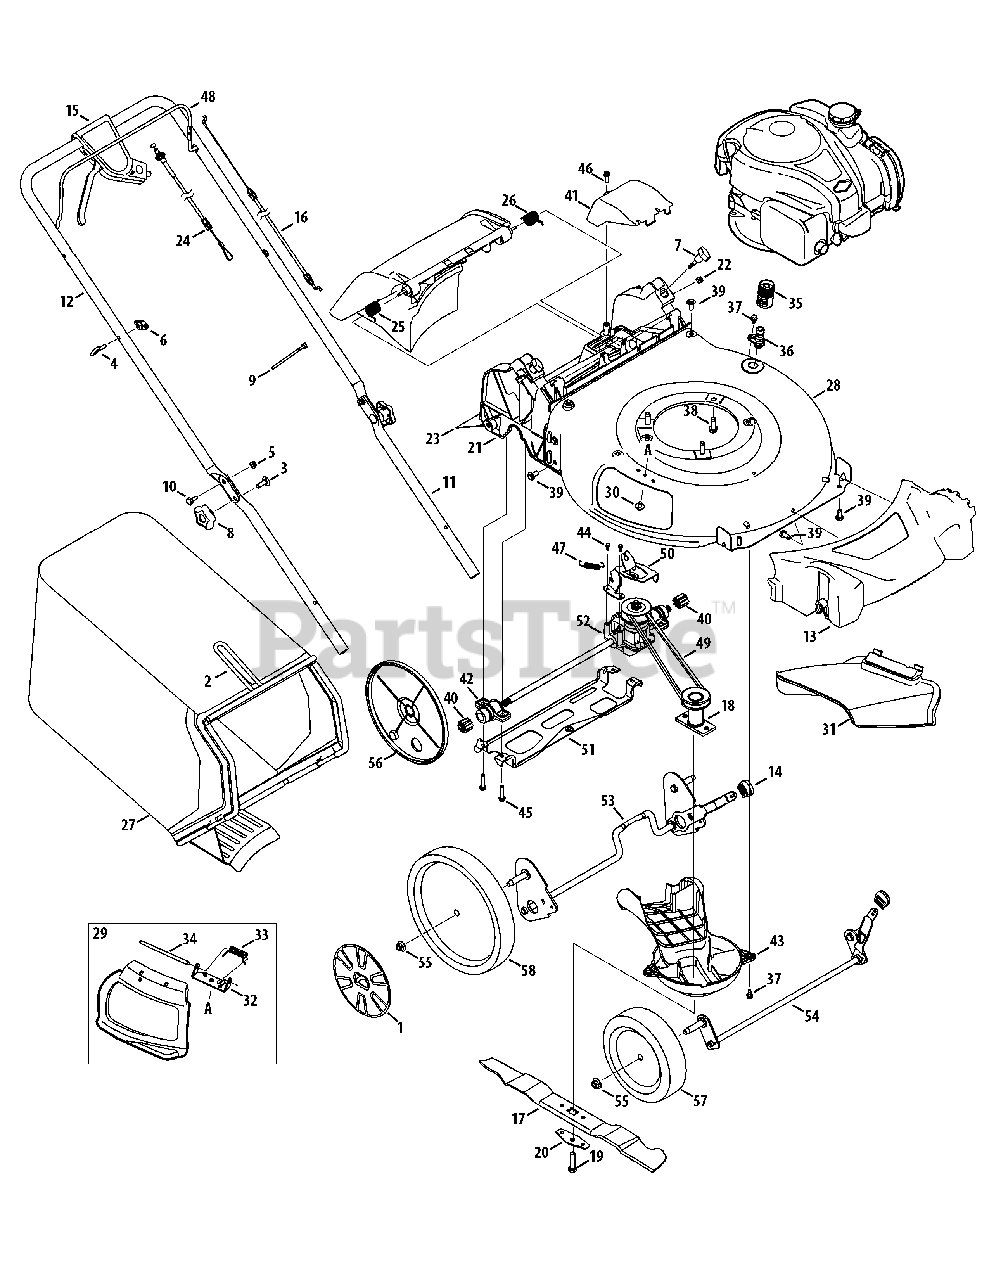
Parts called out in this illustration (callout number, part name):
1	Hubcap - Front
1	Hubcap - Rear
2	Grass Catcher Frame
3	Carriage Screw ,5/16-18
4	Rope Guide
5	Nut, Flange Lock, 1/4-20
7	Wing Knob
8	Star Knob
9	Cable Tie
10	Shdr. Screw, .375 x .126 x 1/4-20
11	Lower Handle
13	Front Cover
14	Adjustment Knob
15	Control Lever Assembly
16	Control Cable
17	Mulching Blade
18	Blade Adapter
19	Screw, 3/8-24 x 1.50
20	Blade Bell Support
21	Rear Discharge Door Assembly
22	Nut, Sq., 1/4-20
23	Trail Shield
24	Drive Cable
25	Torsion Spring - RH
26	Torsion Spring - LH
27	Grass Bag
28	21" Deck
29	Mulch Plug (Incl. 32-34)
31	Side Discharge Chute
32	Chute Deflector Bracket
33	Torsion Spring
34	Hinge Pin
35	Water Nozzle Adapter
36	Water Nozzle
37	Scr., Shldr., 1/4-20 x .50
38	Screw, tt, 3/8-16 x 1.00
39	Screw, 5/16-14 x .750
40	Spur Gear, 9T
41	Transmission Cover
42	Bearing Assembly
43	Engine Baffle
44	Screw, Hex Washer, .159 x .43
45	Screw, 1/4-15 x 1.25
46	Screw, 1/4-15 x .750
47	Exten. Spring, 2.675
48	Blade Control
49	V-Belt
50	Transmission Bracket
51	Rear Support Bracket
52	Transmission
53	Rear Hgt. Adjust./Axle Assembly
54	Front Axle Assembly
55	Flange Lock Nut, 3/8-16
56	Wheel Dust Cover
57	Front Wheel, 8 x2
58	Rear Wheel, 11 x 2
